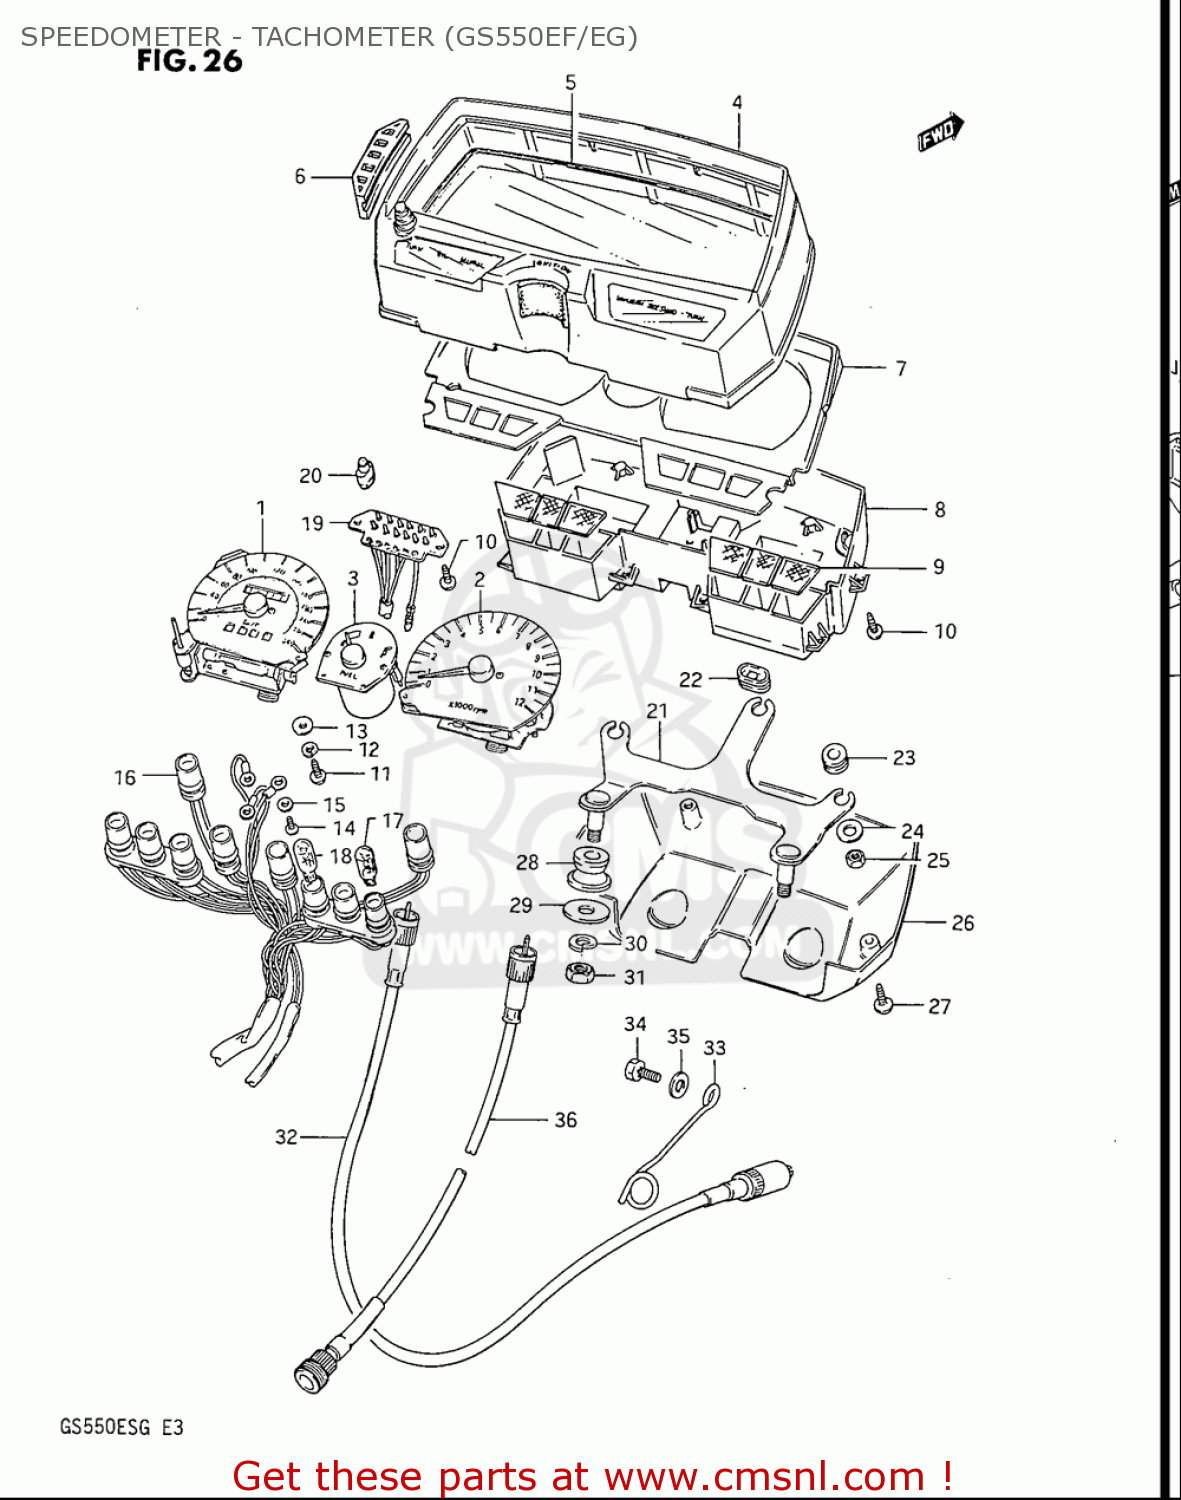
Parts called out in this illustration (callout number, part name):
4	HOOD,METER
5	GLASS,SPEEDOMETER
8	CASE,METER,INNER
10	SCREW,GEAR INDICATOR
11	SCREW
12	WASHER,LOCK
13	WASHER
14	SCREW
15	WASHER
17	BULB(12V3.4W,T10,BF175-01450A)
18	BULB(12V1.7W,T10,WB121)
20	BULB(14V1.12W)
22	CUSHION,METER
23	CUSHION,METER
24	WASHER(5.5X16X1.2)
25	NUT
26	COVER,METER,UNDER
27	SCREW
28	CUSHION,METER BRACKET
29	WASHER(8.5X28X1.6)
30	WASHER,LOCK
31	NUT
32	CABLE ASSY,SPEEDOMETER
33	CLAMP,SPEEDOMETER CABLE
34	BOLT
35	WASHER
36	CABLE ASSY,TACHOMETER
